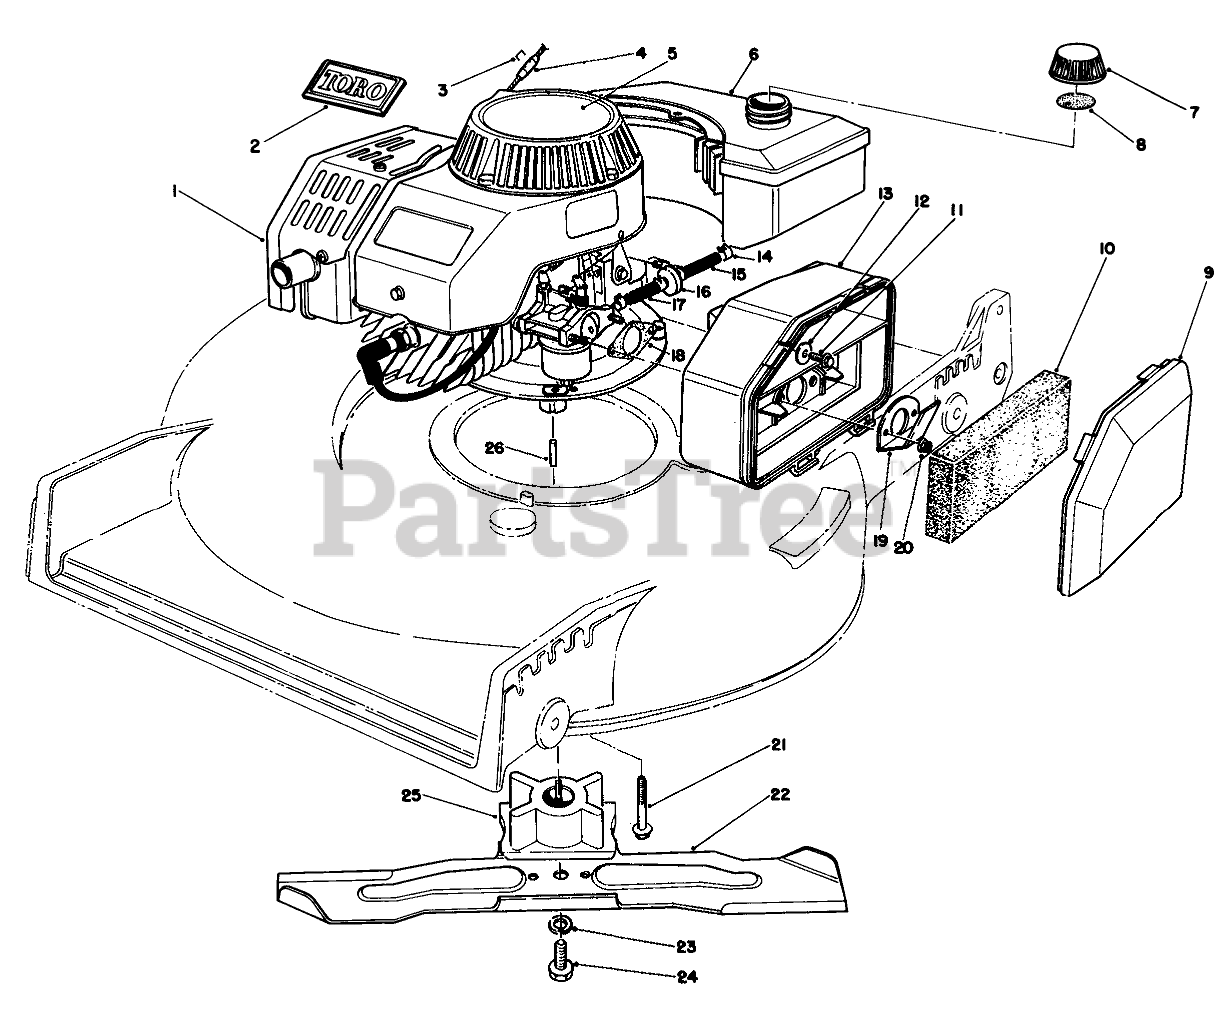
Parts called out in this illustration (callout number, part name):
1	Engine
2	TORO LOGO PLT
3	Staple
4	STOP-ROPE
5	DECAL
6	Gas Tank Assembly
7	Gas Cap Assembly (Incl. Ref. #8)
8	GAS CAP GASKET
9	AIR CLEANER COVER
10	FILTER
11	SCREW-HH
12	WASHER-FLAT
13	AIR CLEANER
14	CLAMP-FUEL LINE
15	HOSE-FUEL
16	FILTER-FUEL
17	HOSE-FUEL
18	GASKET-AIR CLEANER
19	SPIT BACK DEFLECTOR
20	NUT-LOCK
21	SCREW-HHF
22	BLADE-21in
23	WASHER-LOCK
24	SCREW-BLADE
25	Retainer Blade
26	KEY-SQUARE
